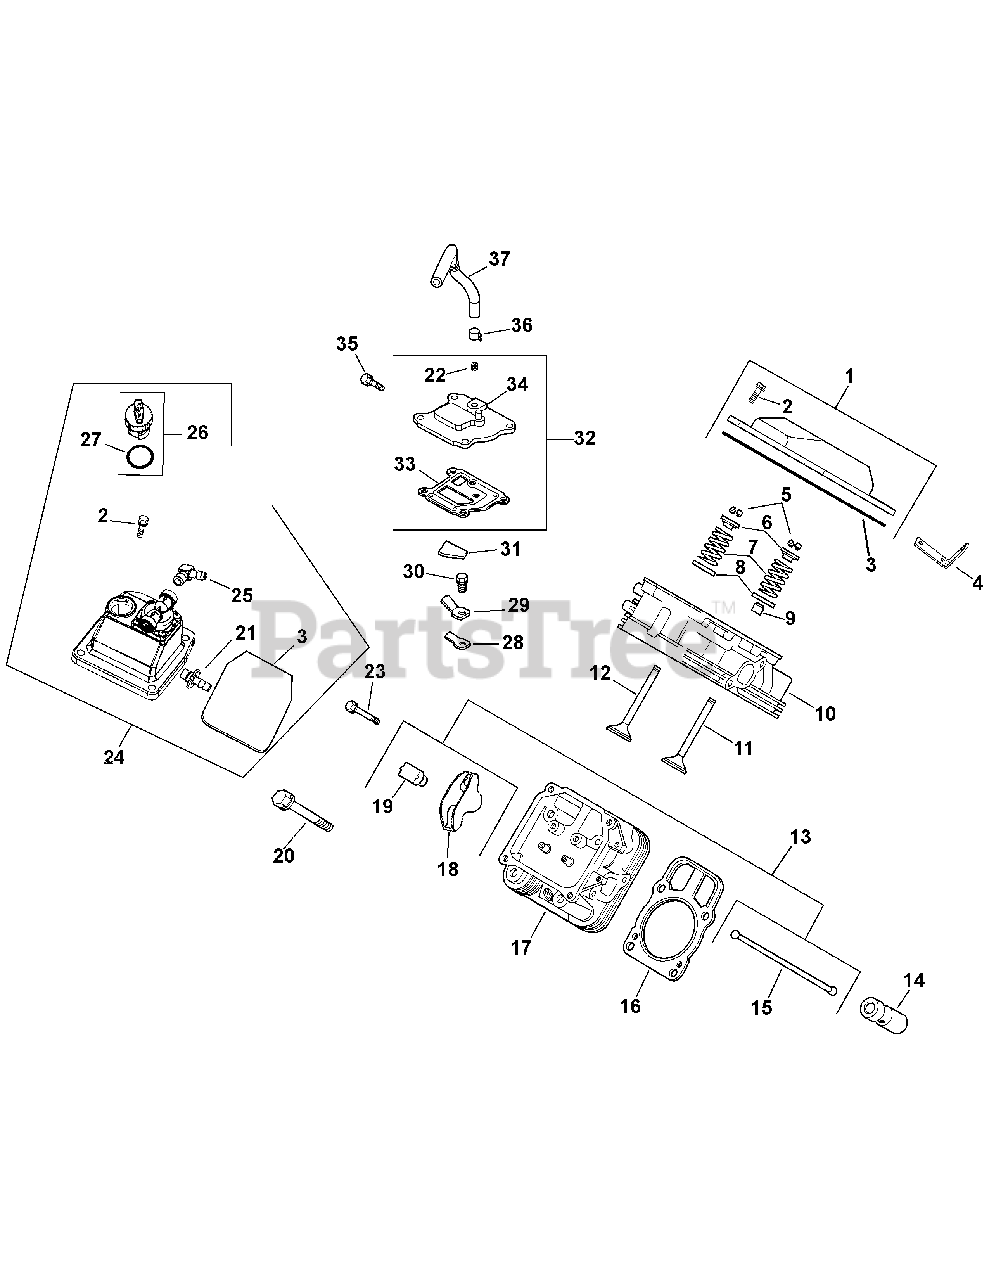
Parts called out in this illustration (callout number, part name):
1	Kit, oil fill rocker cover (Includes 2,3)
2	Screw, hex. Flange M6x1.0x30 (4)
3	O-Ring, valve cover
4	Strap, lifting (2)
5	Kit, retainer (2)
6	Cap, valve spring (2)
7	Spring, valve (2)
8	Retainer, spring (2)
9	Seal, valve stem
10	Head assembly, #1 cylinder
11	Valve, intake (Std.)
11	Valve, intake (.25)
12	Valve, exhaust (Std.)
12	Valve, exhaust (.25)
13	Kit, valve train (Includes 15,18,19)
14	Lifter, valve (4)
15	Rod, push (2)
16	Kit, cylinder head gasket (Includes 21,22) (2)
17	Head assembly, #2 cylinder
18	Arm, rocker (2)
19	Pivot, rocker arm (2)
20	Screw, Flg, M10x1.5x90 (8)
21	Fitting, 45 degrees
22	Plug, ctsk pipe 1/8"
23	Screw, hex. Flange M6x1.0x34 (2)
24	Kit, fuel pump (Includes 2,3,25)
25	Fitting, 90 degrees (2)
26	Cap assembly, oil fill (Includes 27)
27	O-Ring, dipstick
28	Reed, breather
29	Retainer, reed
30	Screw, hex. Flange M5x0.8x10
31	Filter, breather
32	Kit, breathe (Includes 33,34)
33	Gasket, breather
34	Cover, breather
35	Screw, hex. Flange M6x1.0x20 (4)
36	Clamp, hose
37	Hose, breather
